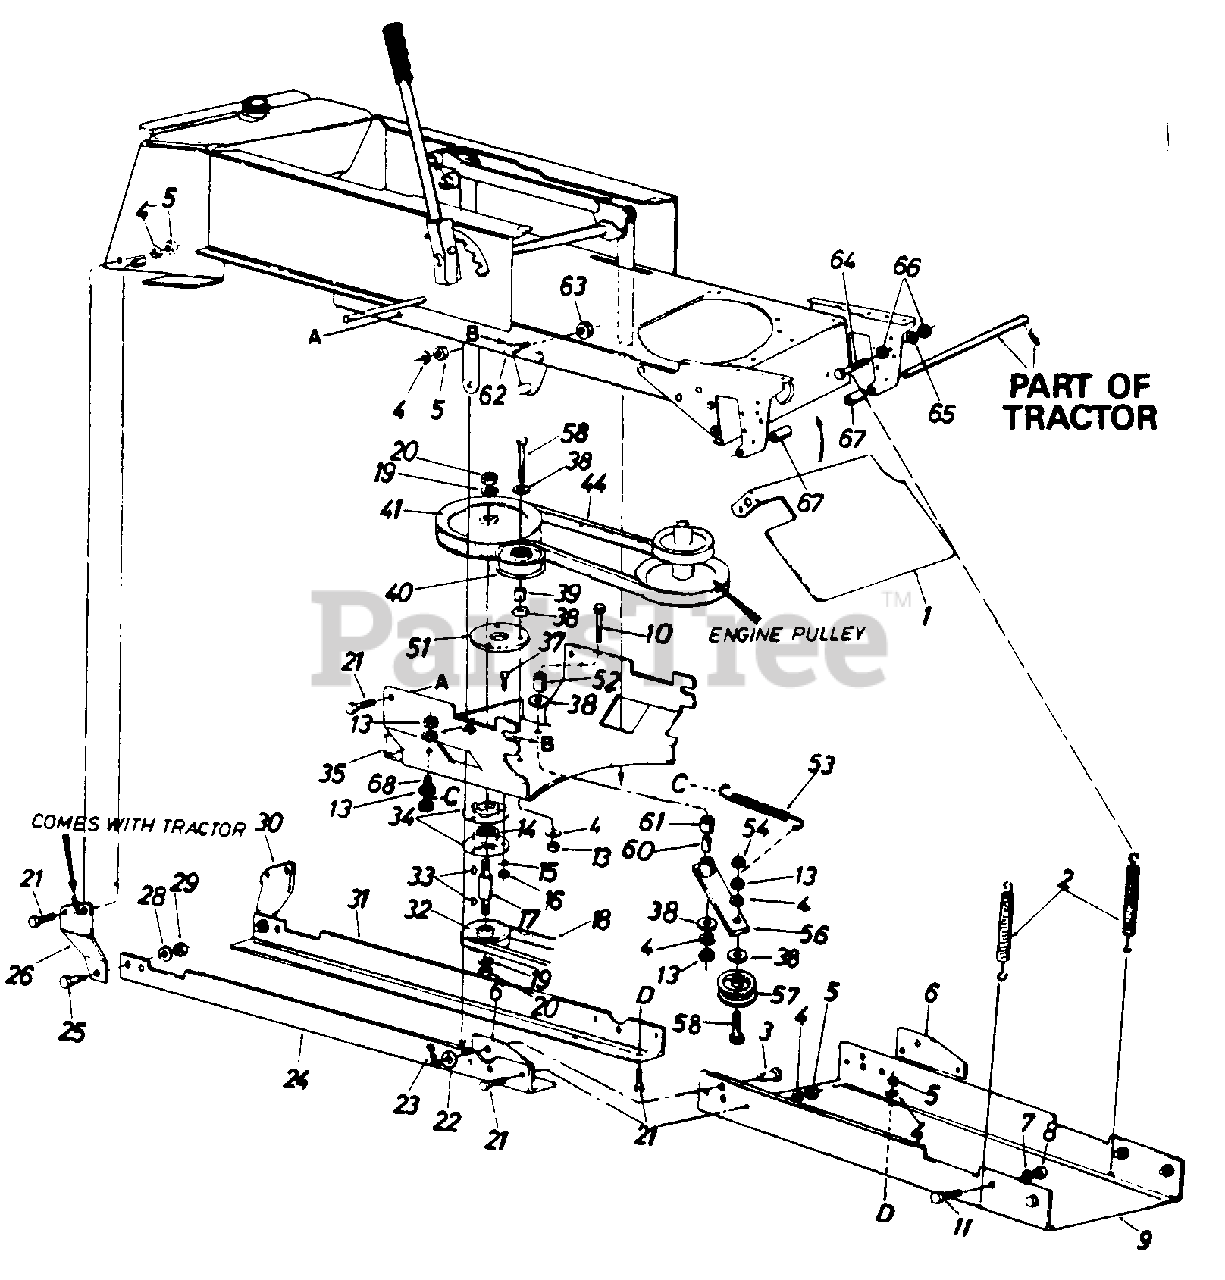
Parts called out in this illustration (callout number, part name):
3	Clevis Pin
4	L.-Wash. 3/8" I.D.
5	Hex L.-Nut 3/8-24 Thd.
6	Attaching Plate
7	L.-Wash. 1/2" I.D.
8	Hex L.-Nut 1/2-20 Thd.
11	Hex Bolt 1/2-20 x 1.25" Lg.
13	Hex J m Nut 3/8-16 Thd.
14	Ball Baring
15	L.-Wash. 5/16" I.D.
16	Hex Nut 5/16-18 Thd.
17	Spindle
18	"V"-Belt
19	L-Wash. 5/8" I.D.
20	Hex Jam Nut 5/8-11 Thd.
21	Hex Bolt 3/8-24 x 1.00" 4.
22	Flat Washer
23	Internal Cotter Pin
29	Hex Nut 7/16-14 Thd.
33	#6 Hi-Pro Key 3/16 x 5/8" Dia.
34	Bearing Housing
35	Supporting Bracket
37	Hex Sems Bolt 5/16-18 x 1"
38	Fl.-Wash. .38" I.D. x 1" O.D.
39	Spacer .38" I.D. x .62' O.D.
40	Fl.-ldhr Pulley
41	Upper Drive Pulley
44	"V"-Belt
53	Extension Spring 4.75" Lg.
54	Hex Cent. L.-Nut 3/8-16 Thd.
56	Idler Arm Ass'y.
57	Idler Pulley
58	Hex Bolt 3/8-16 x 2.25" Lg.
60	Spacsr .377" I.D. x .83" Lg.
61	Spacer .38" I.D. x .565" Lg.
62	Shoulder Bolt .498 Dia.
63	Hex Cent. L-Nut 3/8-16 Thd.
64	Hex Bolt 1/4-28 x 1.50" Lg.
65	L-Wash. 1/4" I.D.
66	Hex Nut 1/428 Thd.
67	Spacer.63" I.Q x 1.75" 4.
68	Hex Bolt 3/8-16 x 2" 4.
